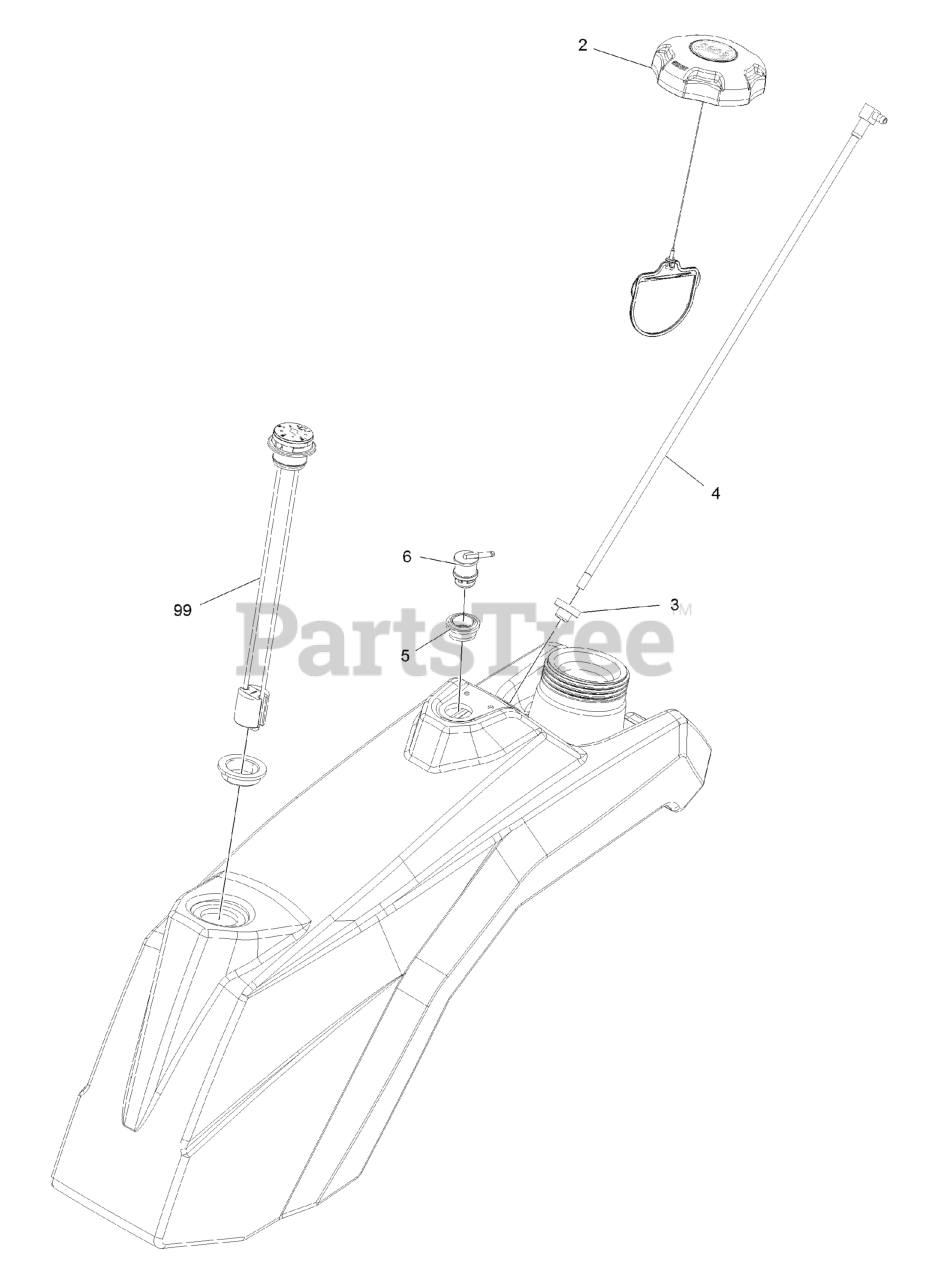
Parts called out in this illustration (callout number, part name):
2	CAP-FUEL, RATCHETING
3	BUSHING
4	STRAW, FUEL, SHORT
5	GROMMET
6	VALVE-VENT, FUEL
99	KIT, FUEL GAUGE
